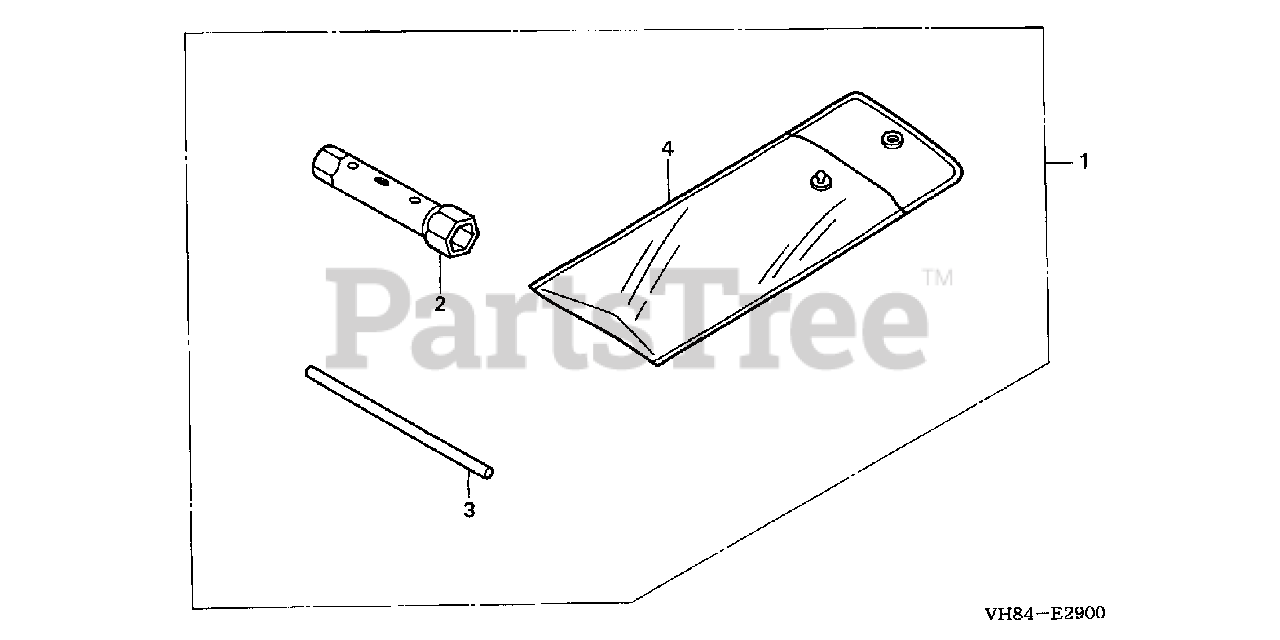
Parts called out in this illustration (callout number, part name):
2	WRENCH, SPARK PLUG
3	BAR A, HANDLE
4	BAG, TOOL (160MM)
